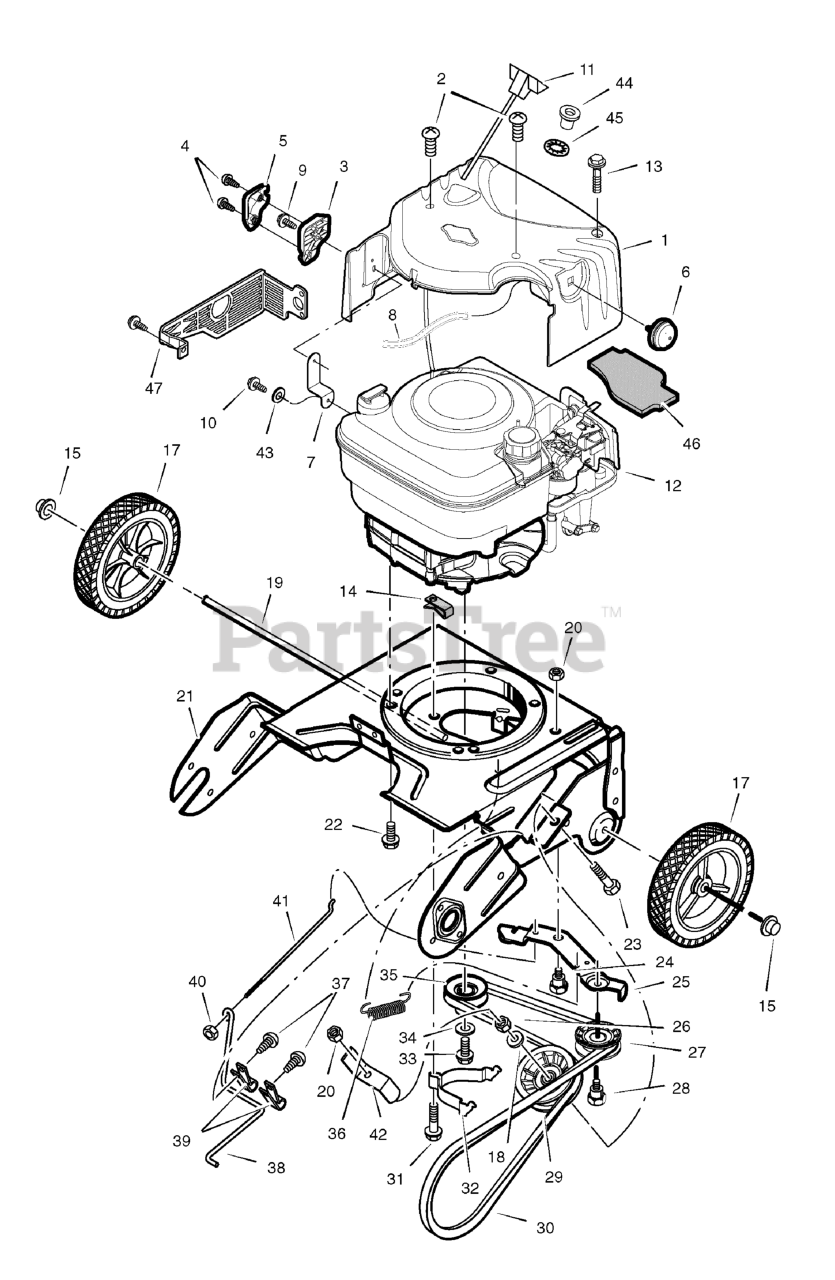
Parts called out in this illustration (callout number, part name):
1	Cover, Top
3	Base, Chute Rod
5	Cover, Chute Rod
6	Primerbulb, Red
7	Bracket, Engine Chute
11	Handle, Starter
12	Engine
14	Retainer
15	Nut, Push Cap
17	Wheel & Tire
18	WASHER, Flat, 13/32
21	Frame, Motor Box
23	Bolt
24	Bolt, Shoulder
25	Bracket, Idler Arm
26	Nut
27	Pulley, V-Belt
28	Bolt, Shoulder
29	Pulley, Flat Idler
32	Guide, Belt
33	Screw
34	Washer
38	Arm, Brake
40	Nut
41	Rod, Adjustment
42	Guide, Belt
43	Lockwasher
44	Guide, Rope
45	Spring Grip Washer
46	Seal, Foam
47	Guard, Muffler
